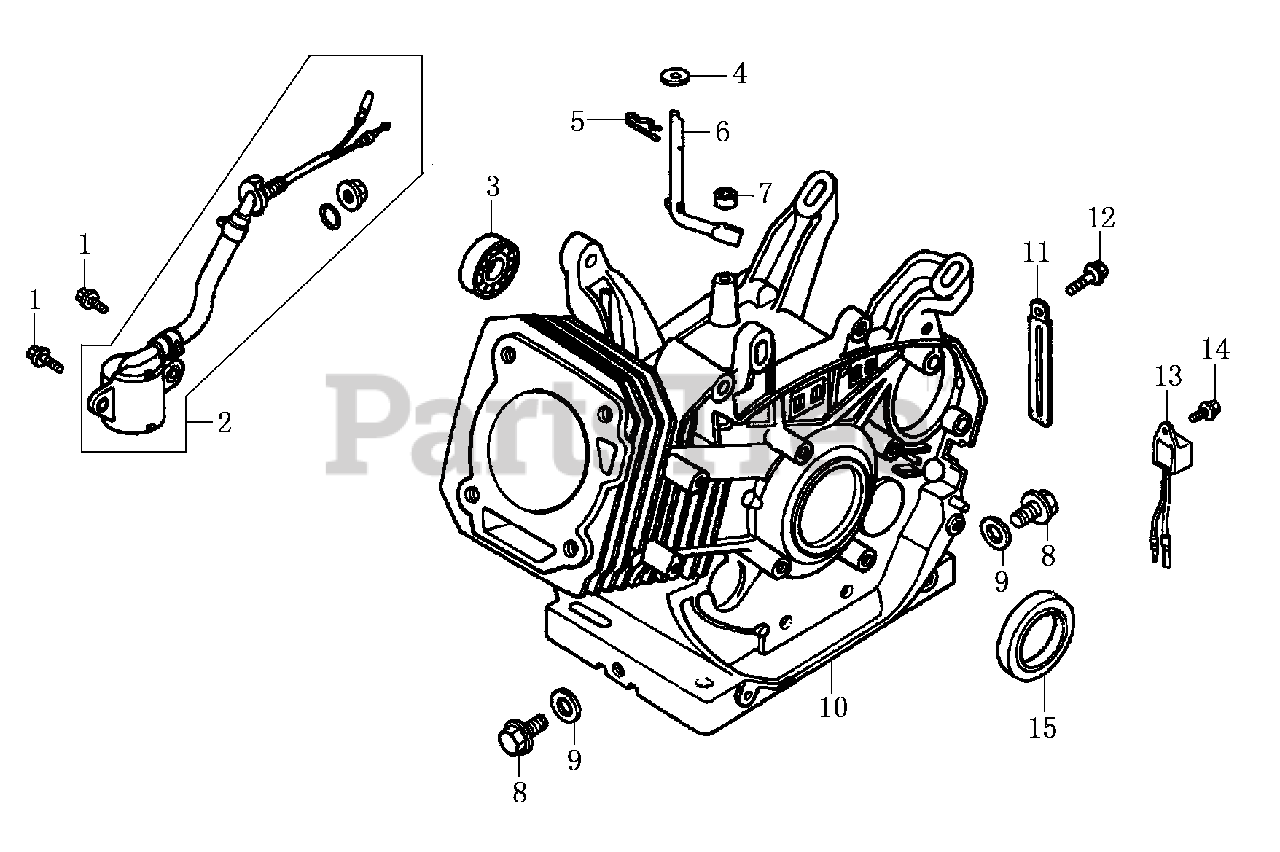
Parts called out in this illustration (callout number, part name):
1	BOLT, FLANGE
2	SWITCH ASSY., OIL LEVEL
3	BEARING, RADIAL BALL 6202
4	WASHER, 8x16x1.2
5	PIN, LOCK, 10MM
6	SHAFT, GOVERNOR ARM
8	BOLT, DRAIN PLUG
9	WASHER, DRAIN PLUG, 12MM
10	CRANKCASE
11	CABLE CLEAT
12	BOLT, FLANGE, 6x12
13	ALERT UNIT, OIL
14	BOLT, FLANGE, 6x12
